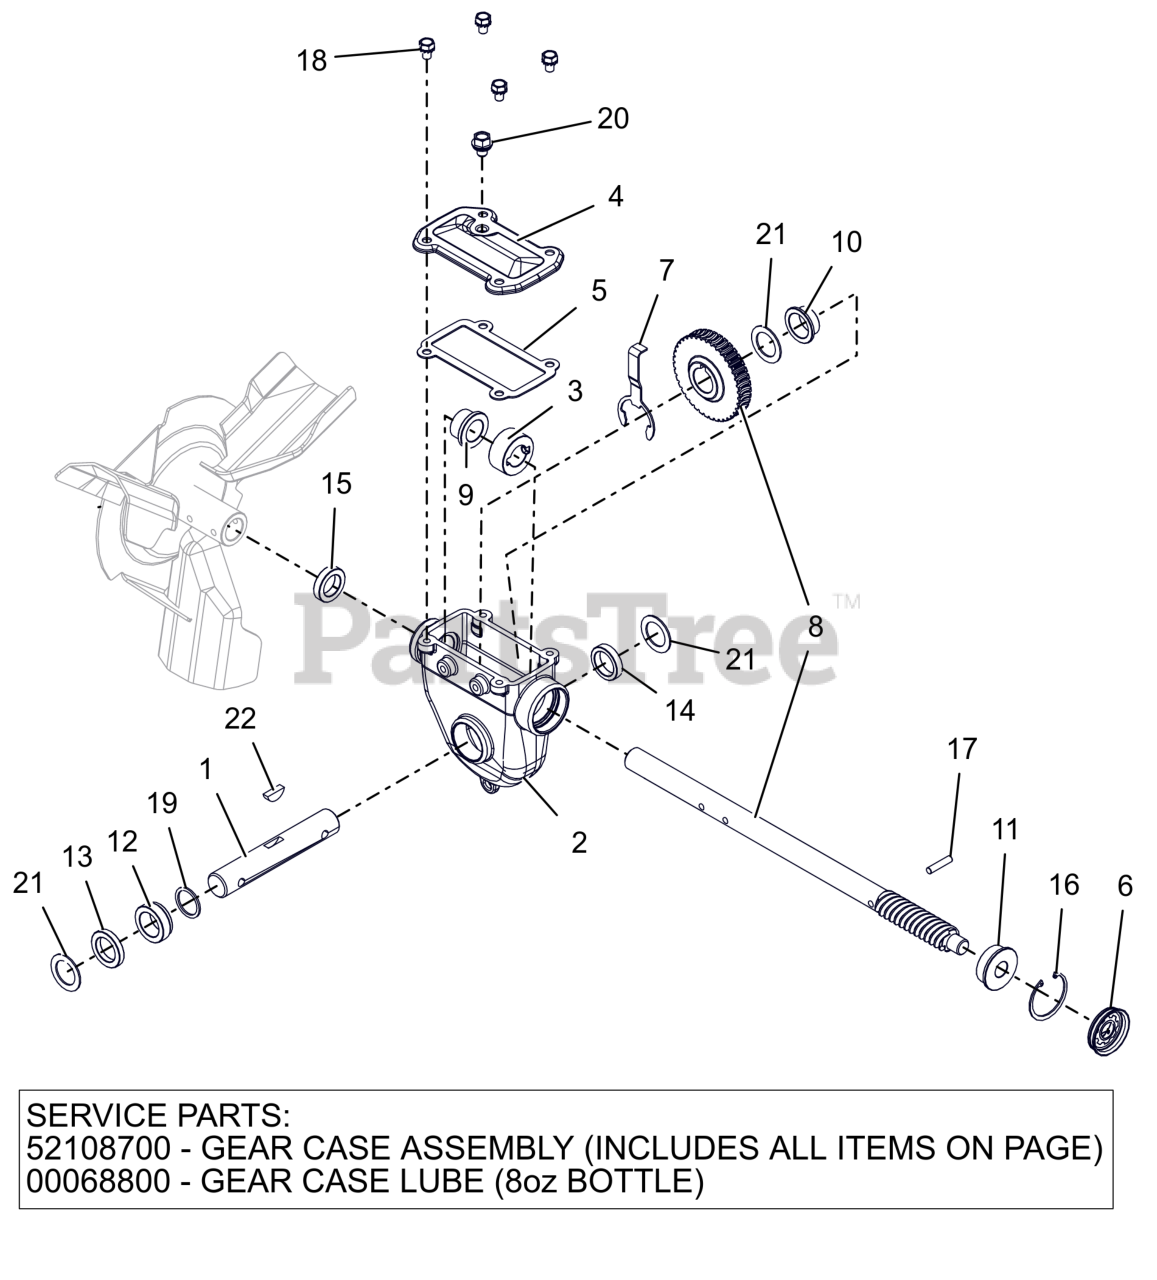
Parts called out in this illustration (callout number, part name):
1	RAKE SHAFT, SHORT-COMMON
2	GEARCASE, LARGE MACHINED
2	KIT, SERVICE - DLX GEAR CASE
2	ARIENS L3 LUBE, 8 OZ BOTTLE
3	THRUST COLLAR, .875"ID SLIPFIT
4	COVER, TOP - LARGE IRON
5	GASKET, TOP - LARGE GEARCASE
6	COVER, GEAR CASE 1.75"
7	BUSHING RETAINER, LARGE
8	KIT, SERVICE-WORM SHAFT & GEAR
9	BSHG-FLG .879X1.128X.75X1.45
10	BSHG-FLG 1.006X1.128X.555X1.45
11	BSHG-FLG .628X1.503X.58X1.725
12	BSHG-FLG LARGE, RIGHT
13	SEAL-OIL .999X1.500X.250 TBC29
14	SEAL-OIL .999X1.375X.312 TBC29
15	SEAL-OIL .873X1.375X.312 TBC29
16	RG-RTNG-INT 1.750X.062
17	PIN-STR .250X1.12 6150
18	BLT, SEMS .31-18X.50 G5 ZCC
19	WSHR, FLT 1.010X1.250X.068 ZCC
20	SCR, .380-15X.500 W/SEAL WASHER
21	WSHR, FLT 1.010X1.505X.062 ZCC
22	KEY-WDRF .25X.875 HRD #A
